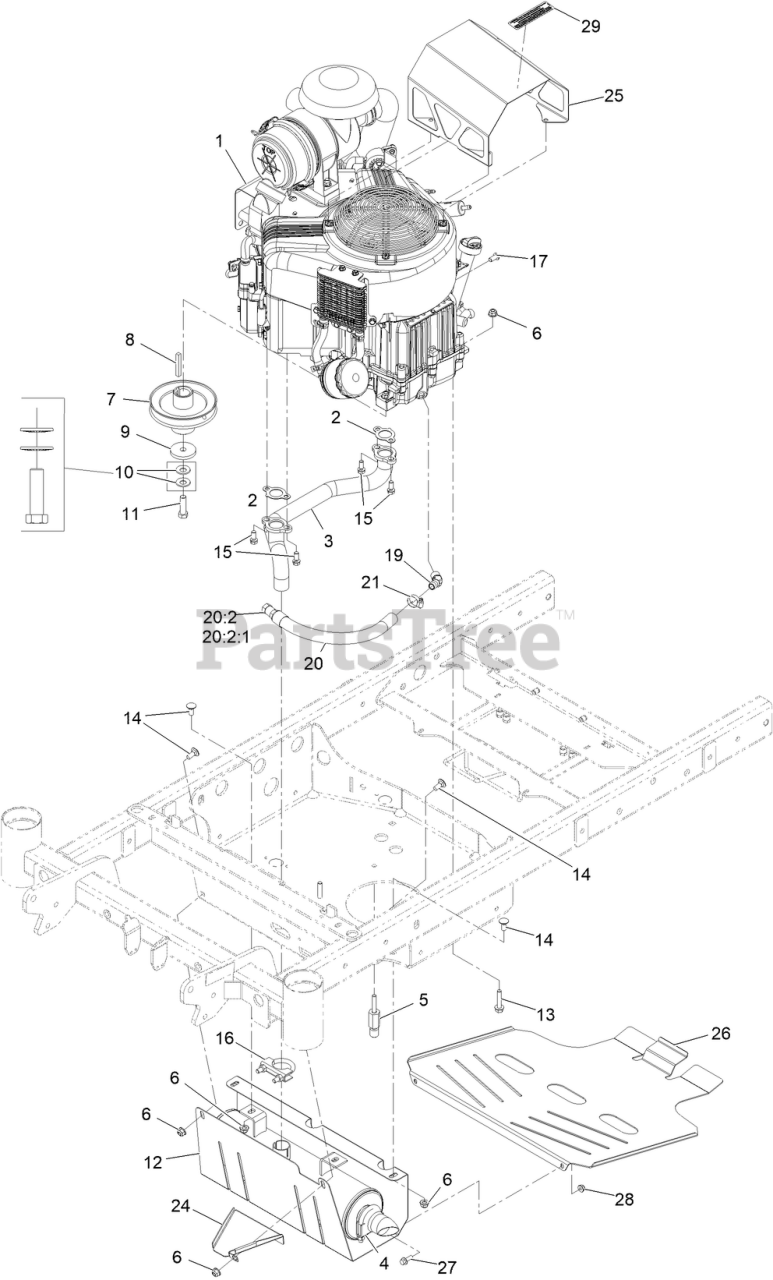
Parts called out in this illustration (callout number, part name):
1	Engine-Vanguard, 21HP Vert.
3	MANIFOLD-MUFFLER
4	MUFFLER
5	PIN-SPRING ANCHOR
6	Nut-Hex Flange
7	PULLEY-ENGINE
9	WASHER-CLUTCH
10	WASHER-SPRING
11	SCREW-HH 7/16-20 X 1 1/2 W/LOCTITE
12	GUARD-MUFFLER
13	5/16-18X 1-1/2 HEX FLANGE
14	SCREW-CARR
15	SCREW-HSBH
16	Clamp-Muffler
17	SCREW-BHTORX
20	OIL DRAIN HOSE W/PLUG
20:2	PLUG-HH
20:2:1	O-RING
21	CLAMP-HOSE
24	PLATE-PAN, OIL
25	COVER-ENGINE
26	PAN-BELLY
27	Screw-HHF
28	Nut-Hex Flange
29	DECAL-ARRESTOR, SPARK
